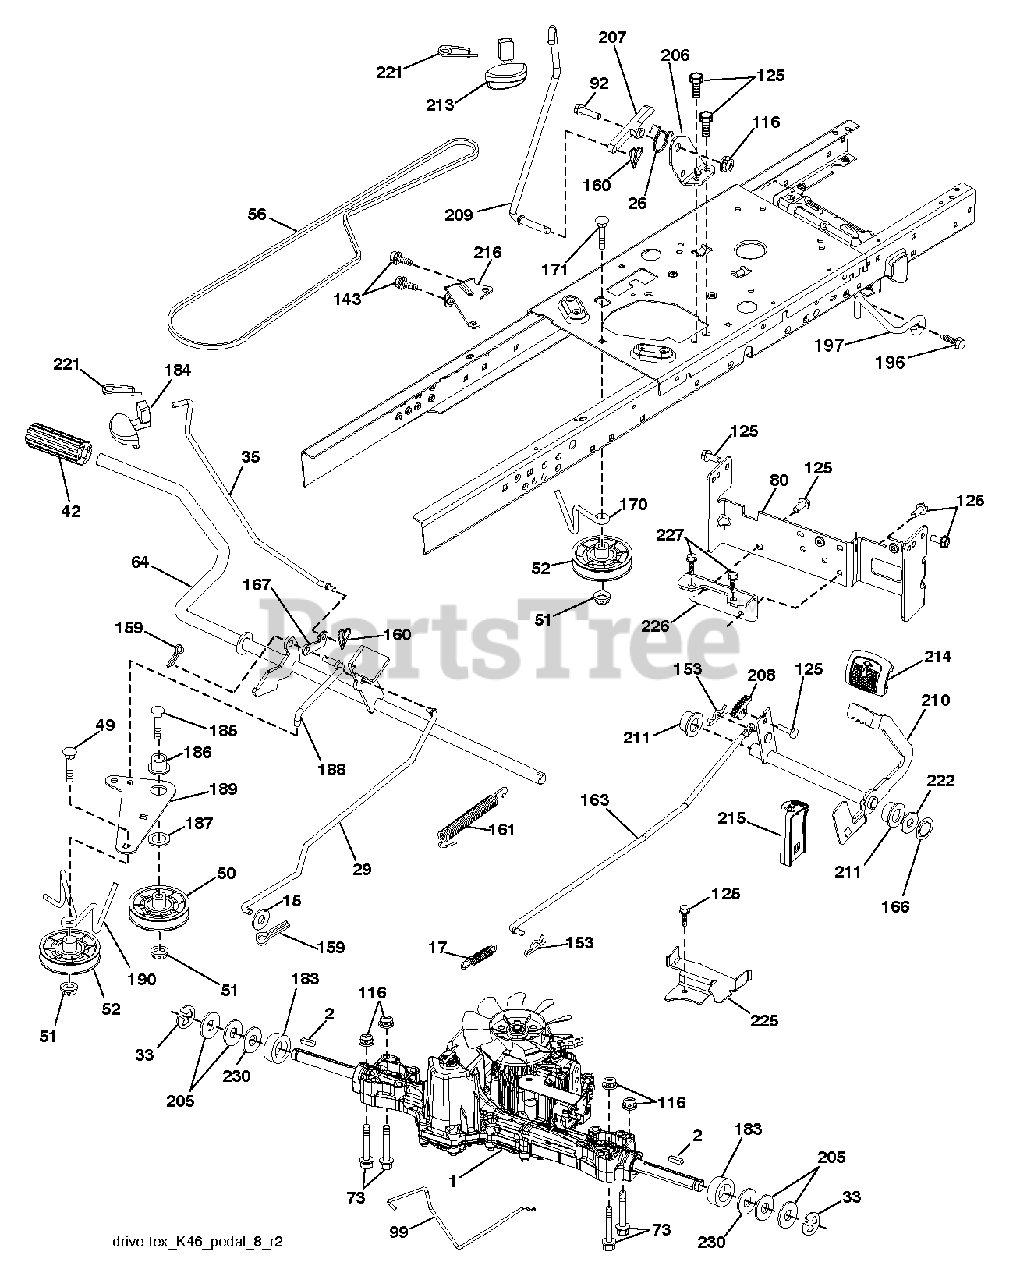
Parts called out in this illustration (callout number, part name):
2	SQUARE KEY
17	SPRING.BRAKE.K46.GREEN
26	SPRING.RETURN.CRUISE
29	ROD.BRAKE.K46
33	E-RING LT
35	ROD.BRAKE.PARKING.LT.T
49	BOLT
50	IDLER.FLAT.910.OFFSET
51	NUT LOCK FLG 3/8-16 UNC
52	IDLER.V-GROOVE.910.OFFSET
56	V-BELT.MOWER.92.40.42/K46
64	SHAFT.ASM.PEDAL.BRK.CNTR
80	STRAP.TORQUE.K46.K57R.TT
92	BOLT
99	ROD.SPRING.BYPASS.K46.LT.Z
116	NUT LOCK HEX FLANGE 5/16-18
125	SCREW
143	SCREW LT
159	COTTER PIN
160	RETAINER CLIP
161	SPRING, RETURN LT
163	ROD.CONTROL.PEDAL.K46
166	NUT.PUSH.625
167	LATCH.BRAKE.SPRING
170	KEEPER.V-IDLER.CENTER.
171	BOLT
183	SPACER AXLE
184	HANDLE.PARKING.BRAKE.LTTEX.667
186	SPACER.RETAINER
187	WASHER 12/32X2X10GA
188	LINK.CLUTCH.GROUND.DRIVE
189	BELLCRANK.GROUND.DRIVE.TEX.
190	KEEPER.BELLCRANK.DRIVE
196	SCREW 3/8-16X1
197	LINK.CLUTCH.ANIT-ROTAT
206	BRKT.MOUNT.LATCH.CRUIS
207	LATCH.CONTROL.CRUISE
208	GEAR.SECTOR.CONTROL.CR
210	ROCKER.ASM.PEDAL.CONTR
211	BEARING.NYLON
213	HANDLE.CONTROL.CRUISE.ELTE
214	PEDAL.FORWARD.PAD.TEX
215	PEDAL.REVERSE.TEX.GT.4
216	BRACKET.PULLEY.IDLER.W/TEX
221	RETAINER.SPRING.CLIP.H
222	WASHER 21/32 X 1-1/4 X 10 GA.
225	KEEPER.BELT.TRANSAXLE.K46
226	BRACKET.MOUNT.TORQUE.K46.TLT
227	Screw, Lt
230	WASHER.HARDENED
